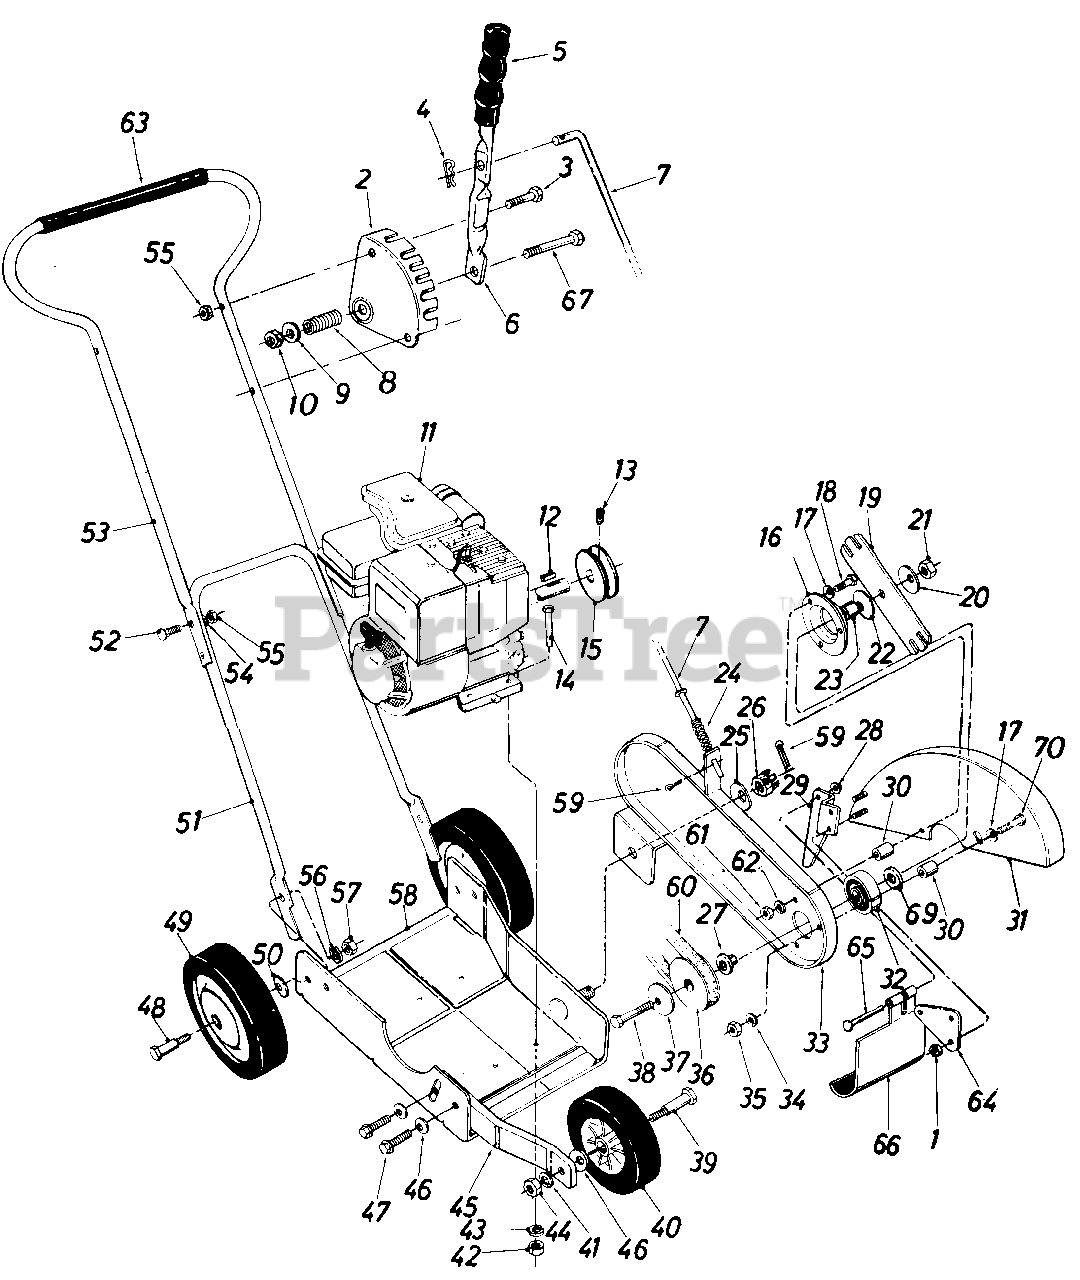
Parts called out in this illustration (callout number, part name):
1	Hex Cent. L.-Nut 1/4-2 Thd.
3	Hex Bolt 1/4-20 x 1.25" Lg.*
4	Cotter Pin 1/8" Dia. x 1.0" Lg.*
5	Grip
7	Clutch Rod
8	Compression Spring.50" O.D. x 1.38" Lg.
9	Fl.-Wash. .34" I.D. x .62" O.D. x.063
10	Hex Cent. L.-Nut 5/16-18 Thd. Engine
11	Engine
12	Sq.Key 3/16 x 1.0" Lg.*
13	Set Scr. 1/4-28 x 1/4" Lq.
14	Hex Bolt 5/16-18 x 1.50' Lg.*
15	Engine Pulley
16	Bearing Housing
17	Bell.-Wash. .34" I.D. x 88" O.D. x .060
18	Hex Bolt 5/16-18 x 1.25" Lg.*
20	Bell.-Wash. .535" I.D. x 1.50" O.D. x.052
21	Hex Cent. L-Nut 1/2-20 Thd .
22	Bell.-Wash. .535" I.D. x 1.50" O.D. x.052
23	Spacer
24	Compression Spring .57" O.D. x 1.92" Lg.
25	Bell.-Wash. .535" I.D. x 1.50" O.D. x.052
26	Hex Castle Nut 1/2-20 Thd.
27	Shoulder Spacer
28	Push Cap
29	Guide
30	Spacer.354" I.D. x .635" O.D. x .510" Lg.
33	Spindle Bracket Ass'y.
34	L.-Wash. 5/16" I.D.*
35	Hex Nut 5/16-18 Thd.
36	Pulley
37	Bell.-Wash. .535" I.D. x 1.50" O.D. x.052
38	Hex Bolt 1/2-20 x 3.50" Lg.*
39	Shoulder Bolt .498" Dia. x 1 .450
40	Wheel Ass'y. Comp. 6" Dia. x 1.50
41	L.-Wash. 3/8" I.D.*
42	Hex ut 5/16-18 Thd.*
43	L.-Wash. 5/16" I.D.*
44	Hex Nut 3/8-16 Thd.*
45	Front Wheel Support
46	Bell.-Wash. .400" I.D. x 88" O.D. x.060
47	Hex Wash. Hd. Self Tap Scr. 3/8- 16 x .75 " Lg.
48	Shoulder Bolt .498" Dia. x 1 .450
49	Wheel Ass'y. Comp. 7" Dia. x 1.50
50	Bell.-Wash. .400" I.D. x 88"O.D.
51	Lower Handle
52	Carriage Bolt 1/4-20 x 1.25"
53	Upper Handle
54	L.-Wash. 1/4" I.D.*
55	Hex Nut 1/4-2 Thd.*
56	L.-Wash. 3/8" I.D.*
57	Hex Nut 3/8-16 Thd.*
58	Base Ass'y.
59	Cotter Pin 1/8" Dia. x 1.0"
60	3V-Belt31.2" Lg.
61	Hex Nut 5/16-18 Thd.
62	L.-Wash. 5/16" I.D.*
63	Grip
64	Flap Bracket
65	Hinge Pin
66	Debris Deflector
67	Hex Bolt 5/16-18 x 1.75" Lg.*
69	Fl.-Wash. .51 I.D. x 1.00 O.D. x.060
70	Hex BOIL 5/16-18 x 2.00" Lg.*
